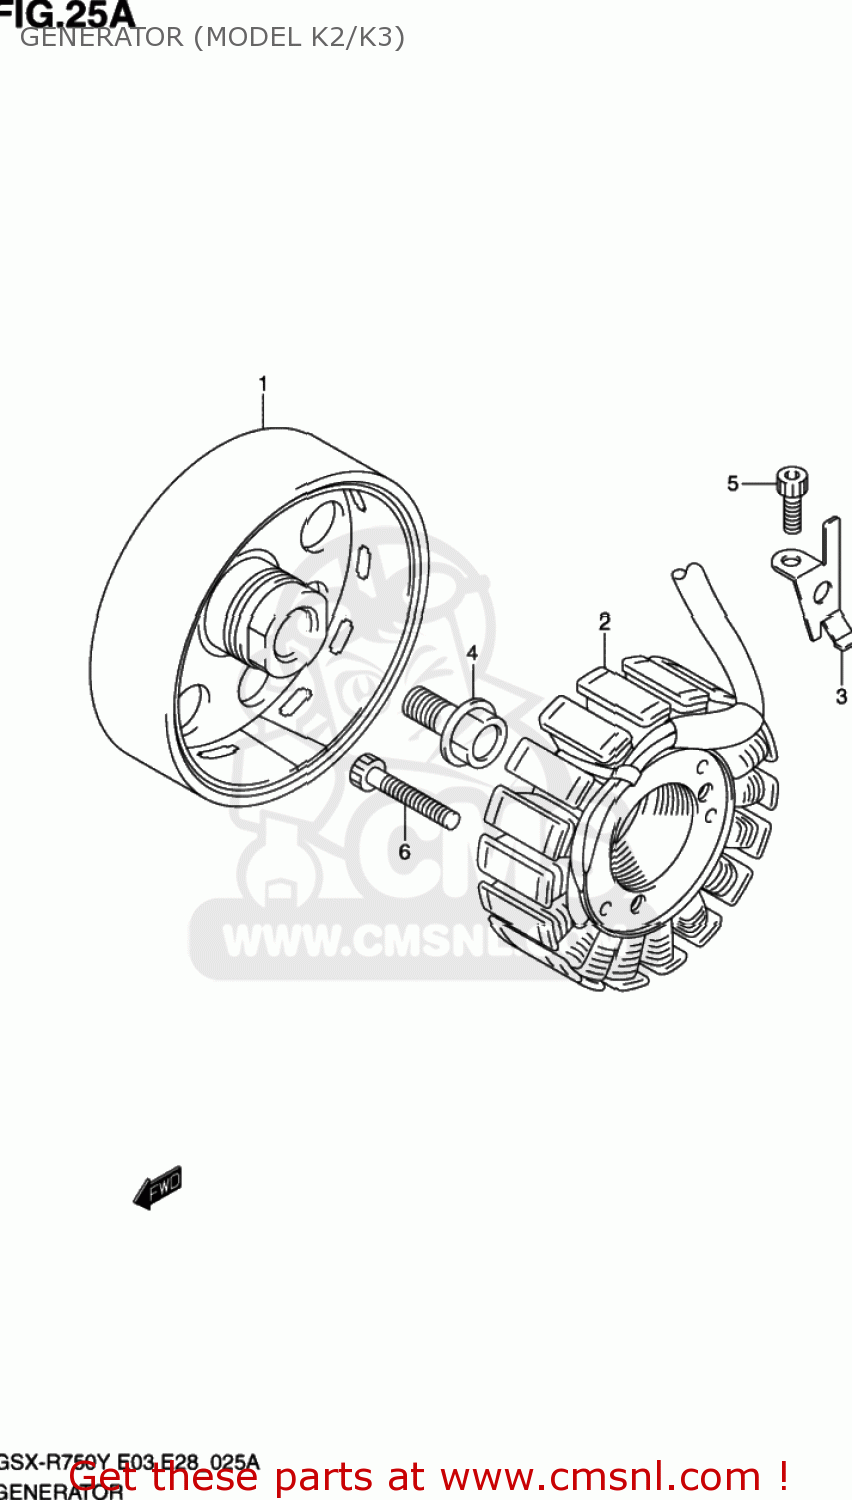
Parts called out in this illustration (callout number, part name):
1	ROTOR ASSY
2	STARTER ASSY
3	CLAMP,MAGNETO LEAD
4	BOLT(12X23)
5	BOLT,STRANGER
6	BOLT
